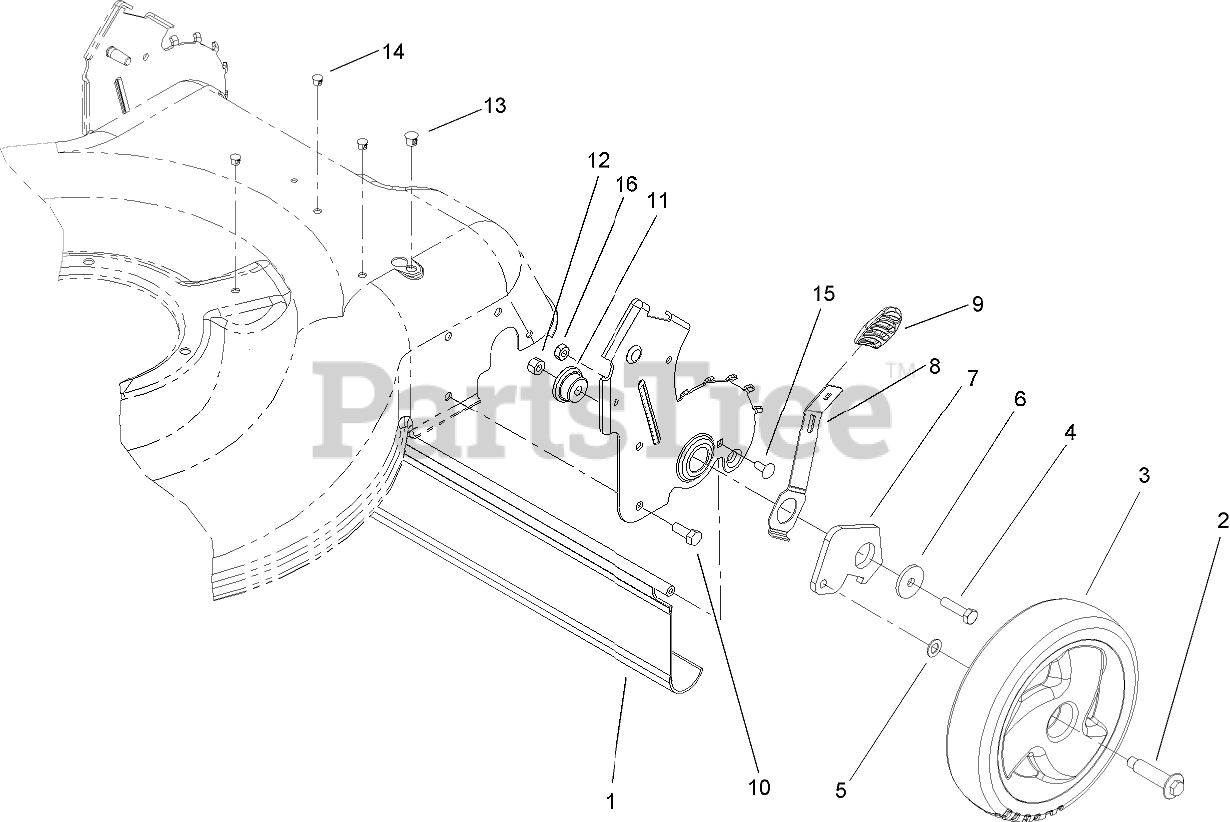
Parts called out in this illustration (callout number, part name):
1	Shield-Trailing
2	BOLT-SHOULDER
3	WHEEL ASM (59505)
4	SCREW-HH
5	WASHER
6	Washer-Flat
7	Arm-Pivot, Rear (LH)
8	Arm-Spring
9	Knob-Lever, HOC
10	SCREW-HH
11	Bushing-Mount, HOC
12	NUT-LOCK, NI
13	Plug-Dome
14	Plug-Dome
15	SCREW-CARR
16	NUT-LOCK, NI
